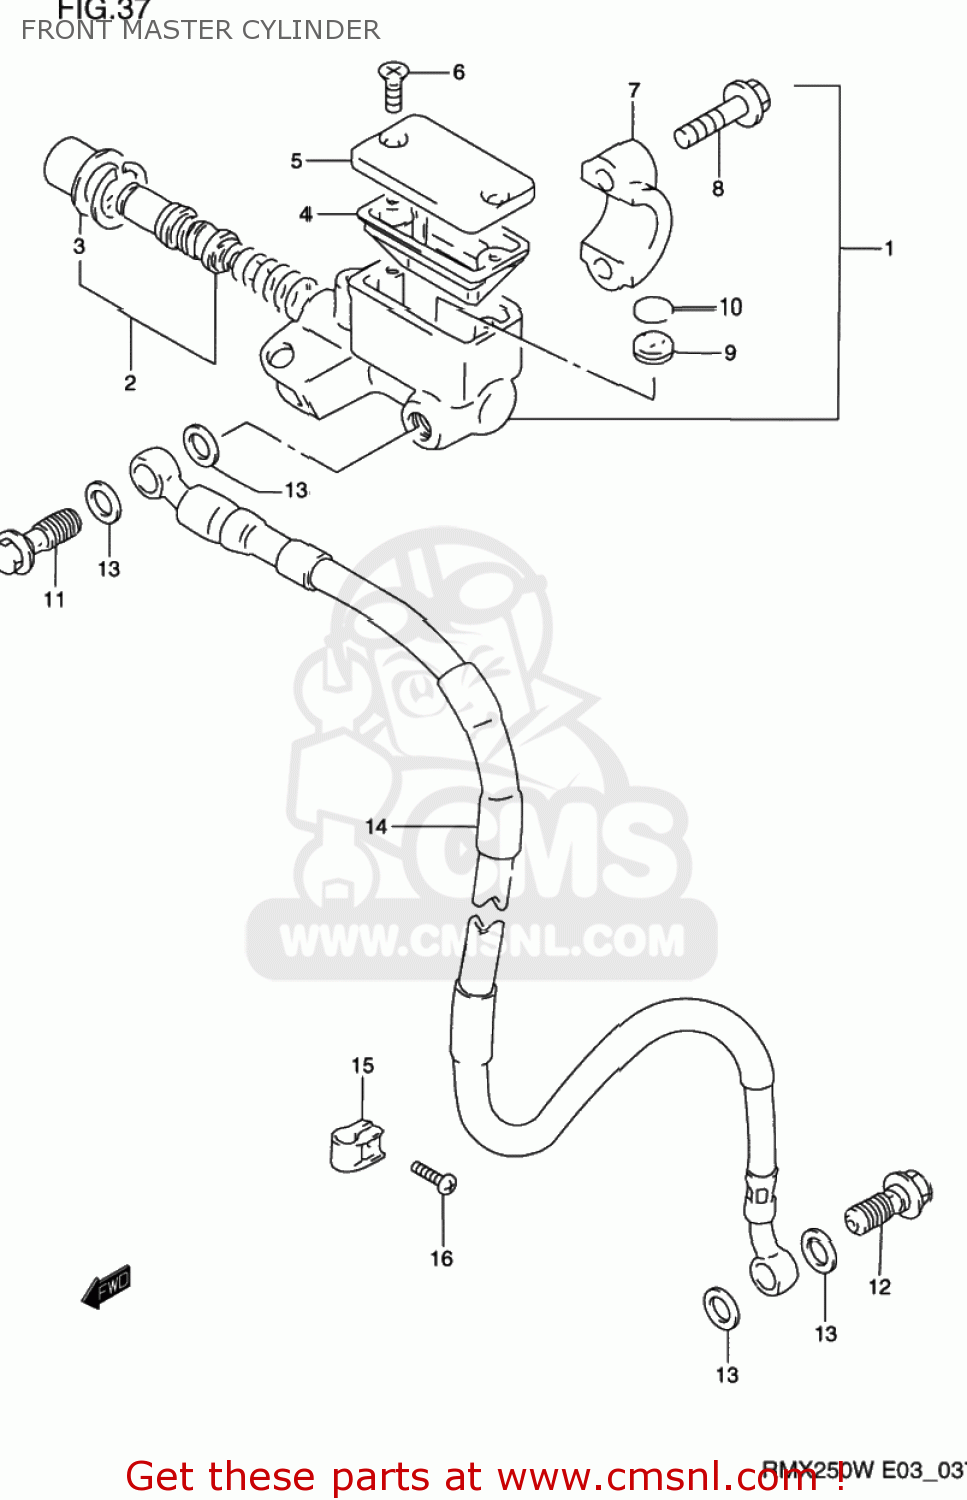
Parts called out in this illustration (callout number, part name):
1	CYLINDER ASSY,FR MASTER
2	PISTON & CUP SET
3	BOOT
4	DIAPHRAGM
5	CAP
6	SCREW
7	HOLDER
8	BOLT
9	SEPARATOR
10	RING
11	BOLT UNION
12	BOLT UNION
13	WASHER(10X15X1.5)
14	HOSE,FR BRAKE
15	CLAMP,FR BRAKE
16	SCREW
